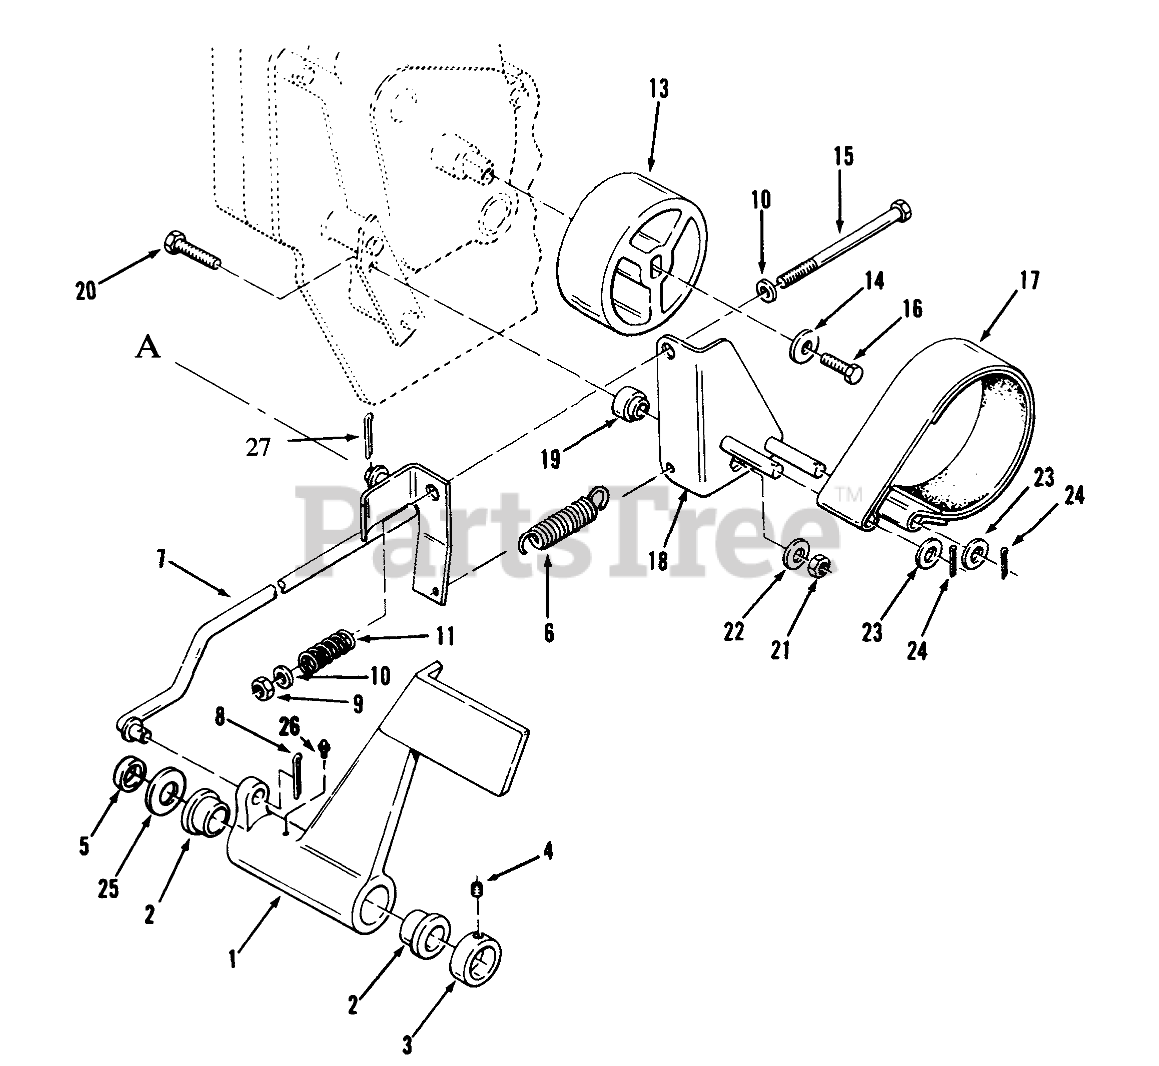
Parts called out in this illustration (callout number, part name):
1	Pedal-Brake
2	BUSHING
3	COLLAR
4	SCREW-HSH
5	SPACER
6	SPRING
7	ASY BRAK RD WAR
8	PIN-COTTER
9	NUT-LOCK, NI
10	WASHER-FLAT
11	SPRING-COMPRESSION
13	DRUM-BRAKE
14	WASHER
15	SCREW-HH
16	SCREW-HH, LOCK
17	ASSY-BRAKE BAND
18	WA-BRAKE PIVOT B
19	BUSHING-BRAKE PIVOT
20	SCREW-HH
21	NUT-LOCK, NI
22	WASHER-FLAT
23	WASHER-FLAT
24	PIN-COTTER
25	WASHER
26	FITTING-GREASE
27	Hairpin
